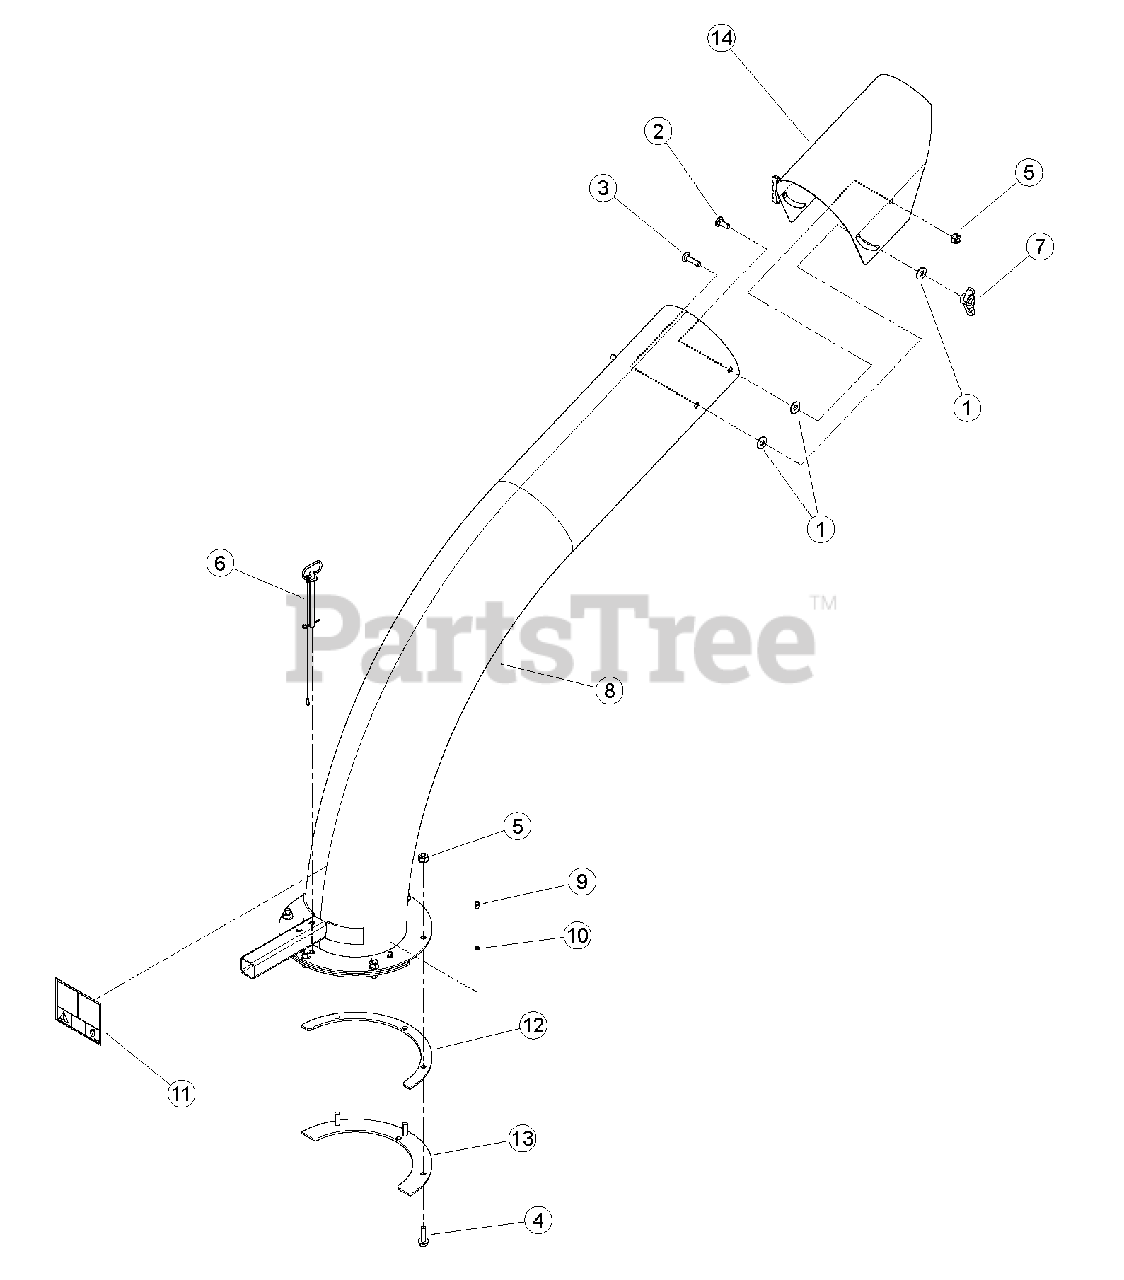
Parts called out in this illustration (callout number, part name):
1	WASHER, 3/8" FLAT ZP
2	BOLT, 3/8 X 1" GR5 CRG NC ZP
3	BOLT, 3/8 X 1-1/2" GR5 CRG NC ZP
4	BOLT, 3/8 X 1-1/4 FLANGE NC
5	NUT, 3/8-16 NYLOCK FLANGE
6	PIN, 3/8 X 4.25" DISCHARGE
7	KNOB, 3/8-16 UNC FEMALE TEE
8	ASSEMBLY, 8 INCH DISCHARGE CHUTE
9	FITTING, 1/4 SELF-TAP GREASE
10	WASHER, FLAT .254X.400X.048
11	DECAL, DISCHARGE DEBRIS & LOCK
12	RING, DISCHARGE SPACER
13	RING, DISCHARGE CLAMP
14	CAP, 8 INCH DISCHARGE CHUTE
